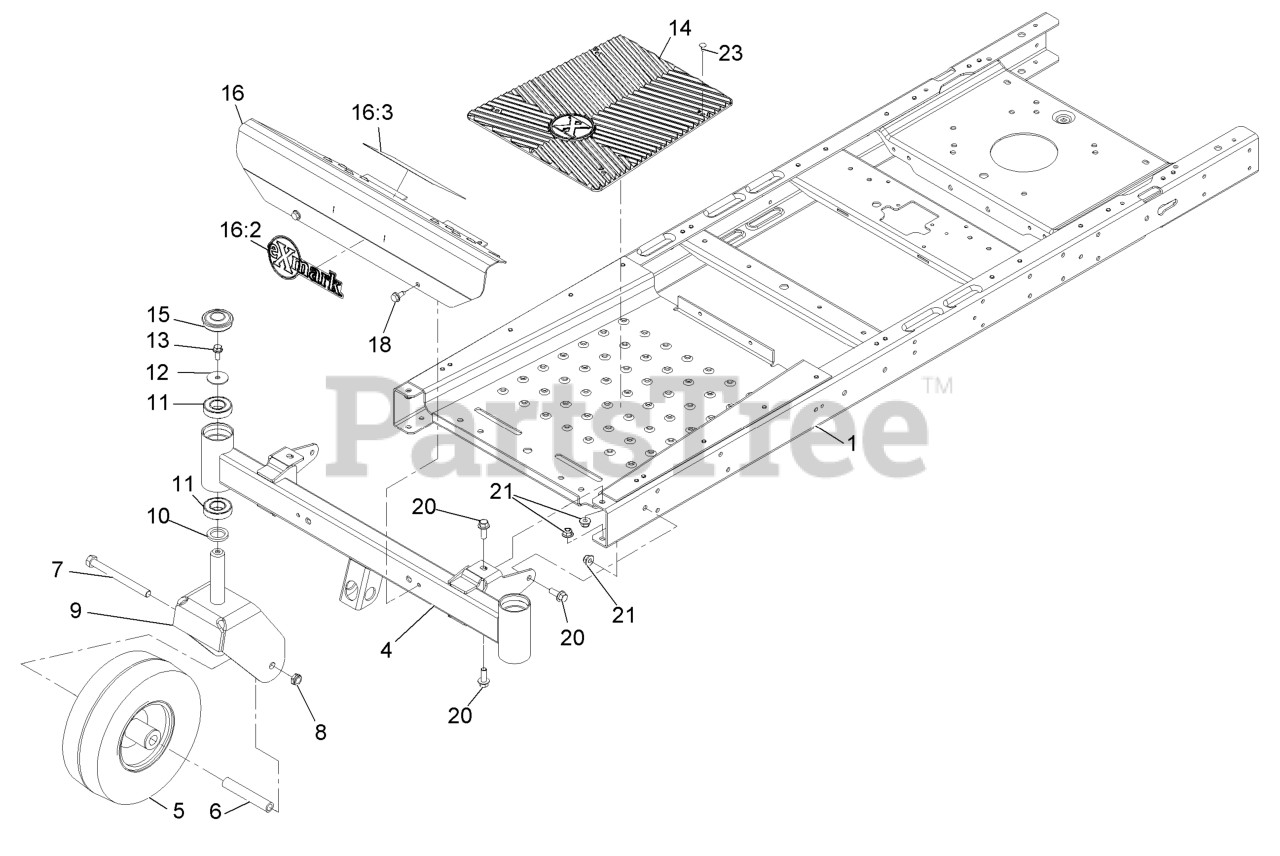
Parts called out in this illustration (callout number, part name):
1	FRAME ASM
4	AXLE-FRONT, NARROW
5	CASTER WHEEL ASM
6	BUSHING-SPANNER
7	SCREW-HH
8	NUT-HEX
9	FORK-CASTER
10	WASHER-THRUST
11	BEARING-BALL
12	WASHER-FLAT
13	SCREW-HHF
14	FLOOR MAT- EXMARK
15	CAP-GREASE
16	FOOTREST ASM
16:2	DECAL-EXMARK LOGO
16:3	DECAL-DANGER
18	Screw-HWH 5/16-18 X 3/4 Tf
20	SCREW-HHF 3/8-16 X 1
21	NUT-HF, NI
23	PLUG-PLASTIC
